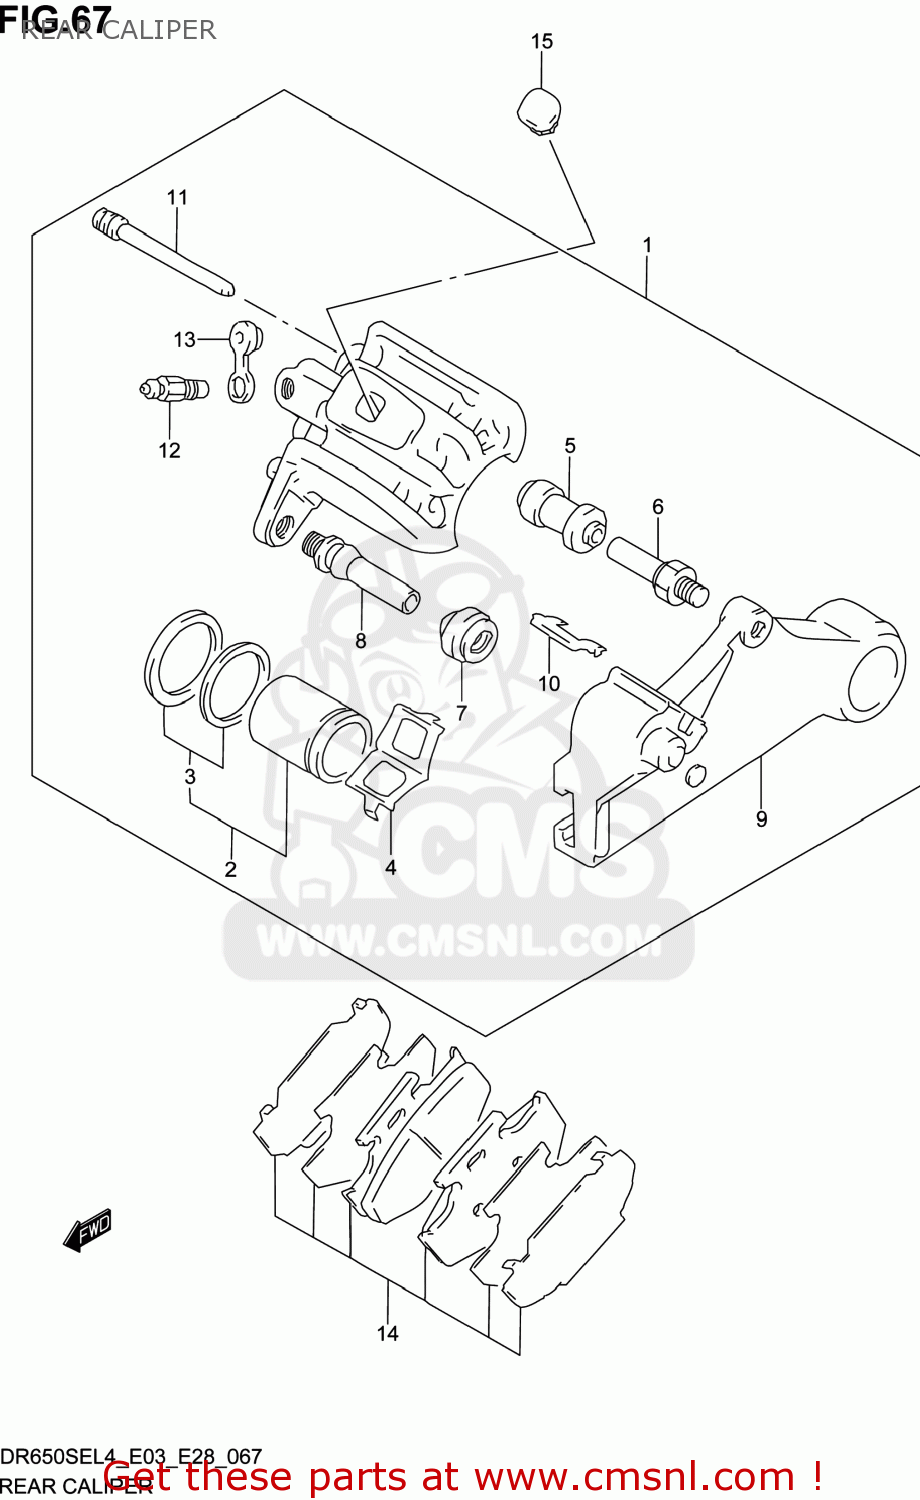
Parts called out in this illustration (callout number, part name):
1	CALIPER ASSY,RR
2	PISTON SET
3	SEAL SET,PISTON
4	SPRING,PAD
5	BOOT
6	BOLT
7	BOOT
8	PIN
9	BRACKET
10	RETAINER,BRACKET
11	PIN,HANGER
12	BLEEDER
13	CAP,BLEEDER
14	PAD & SHIM SET (NAS)
15	COVER,RR CALIPER BODY
